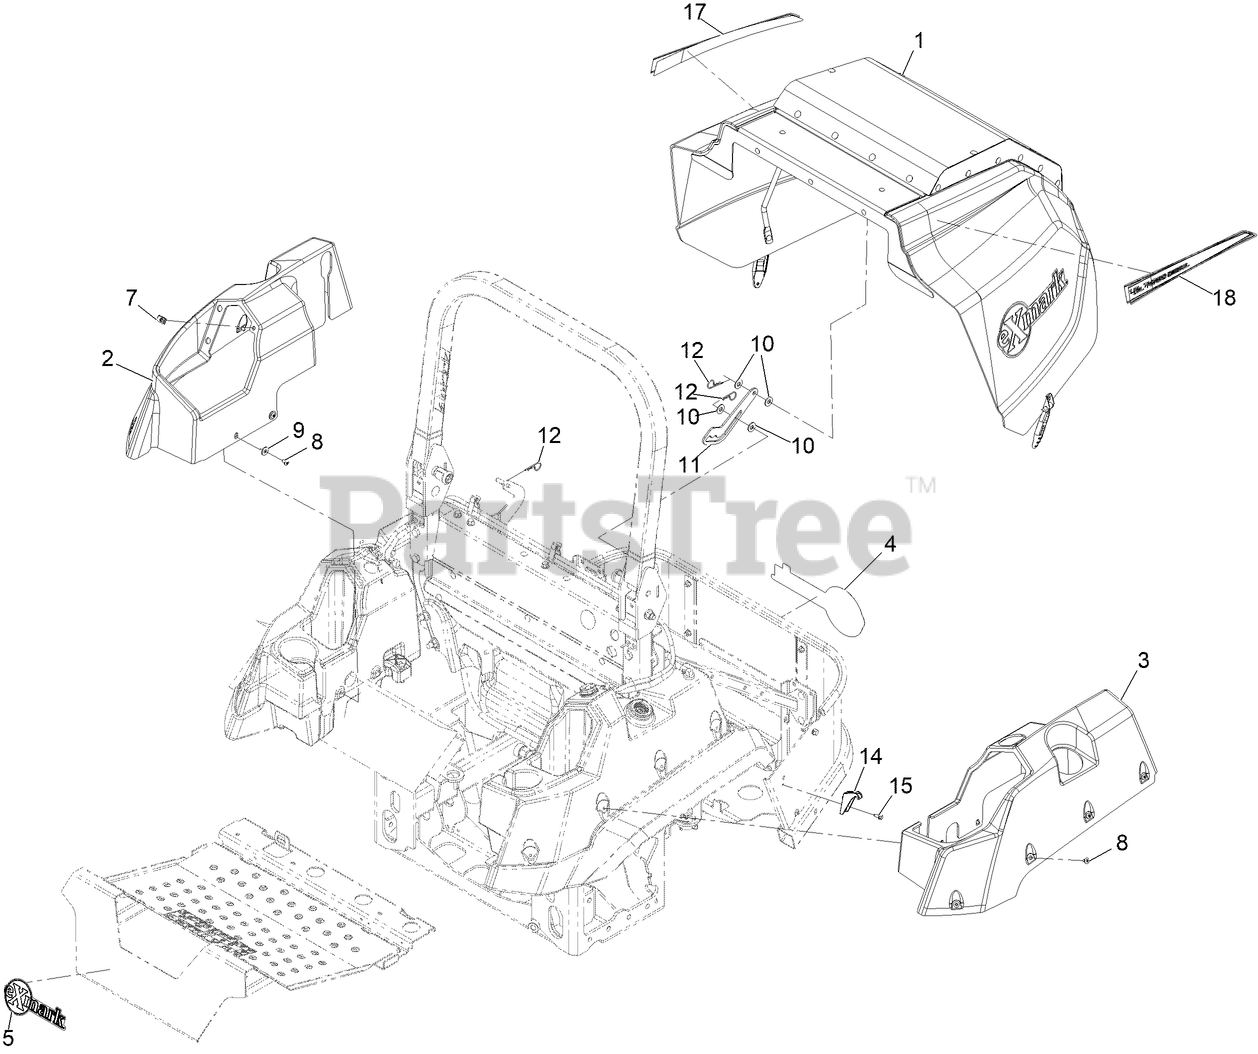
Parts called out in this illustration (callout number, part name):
1	ASM, HOOD LZSD
2	COVER-TANK, RH
3	COVER-TANK, LH
4	DECAL-EXMARK
5	DECAL-EXMARK
8	SCREW-TORX
9	WASHER-FLAT
10	WASHER-FLAT
11	PROP-HOOD
12	PIN-COTTER, HAIR
14	LATCH-CATCH
15	SCREW-HWH
17	DECAL-TURBO DIESEL-RH
18	DECAL-TURBO DIESEL-LH
